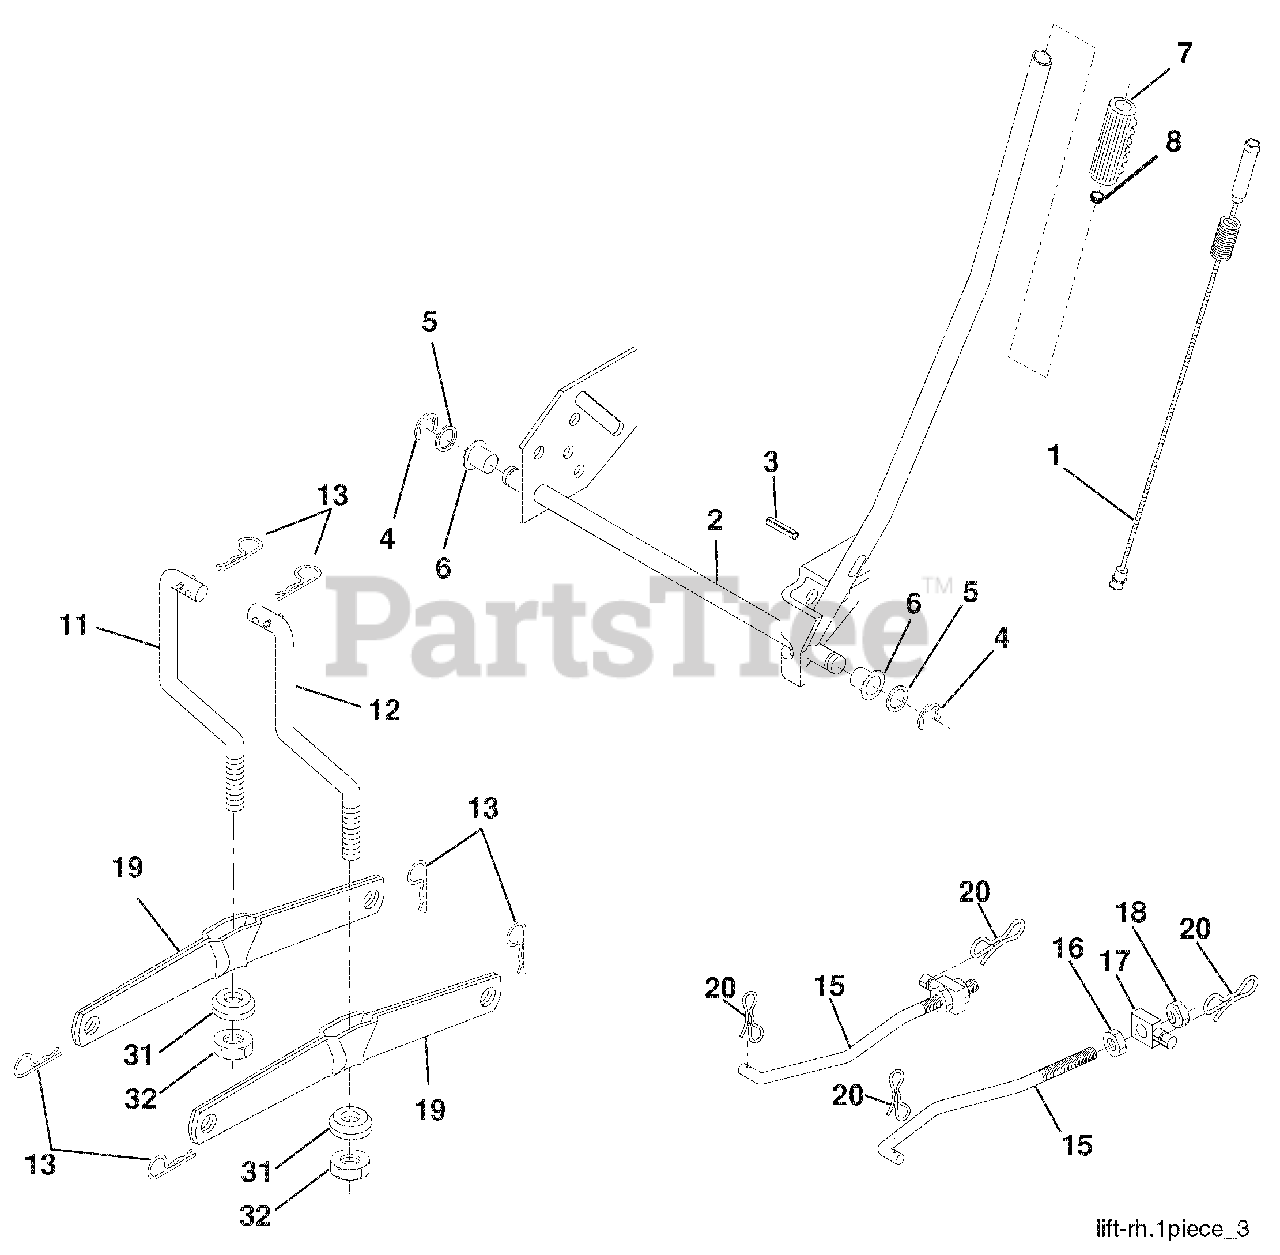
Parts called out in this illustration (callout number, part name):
1	PLUNGER ASM LIFT LEVER
2	SHAFT ASM LIFT RH
3	PIN GROOVE 1 500 ZINC
4	E RING #5133-62
5	WASHER 21/32 X 1 X 21 GA.
6	BEARING.NYLON.BLK..629 ID.
7	WASHER 21/32 X 1 X 21 GA.
8	BUTTON PLUNGER BLACK
11	LINK LIFT LH FIXED LENGTH
12	LINK LIFT RH FIXED LENGTH
13	Retainer Spring
15	LINK FRONT
16	NUT JAM HEX 1/2-13 UNC
17	TRUNNION
18	NUT LOCK W/WSH 1/2-13 UNC
19	ARM SUSPENSION REAR
20	PIN.COTTER.7/16.BOW TIE LOCK
31	BEARING PVT LIFT
32	NUT.CROWNLOCK.3/8-24
